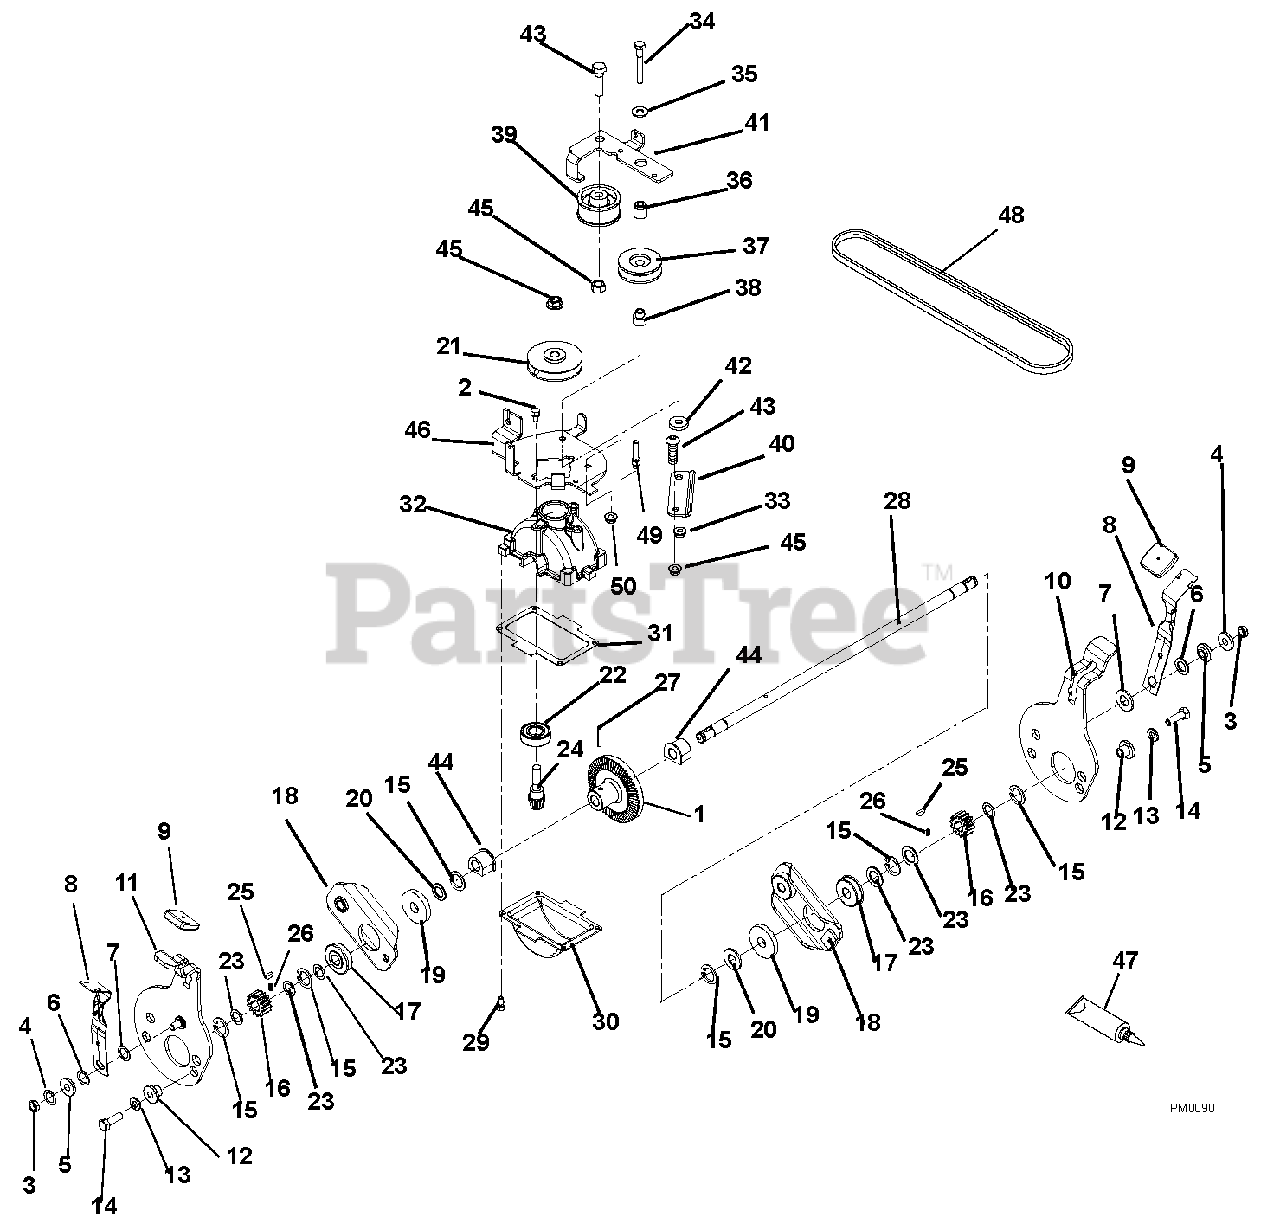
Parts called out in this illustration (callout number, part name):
1	Gear, Reduction
2	Screw, Tapping 10-24 x .375 Hex Washer Head Thread Rolling
3	Nut, Locking-Center .31-18
4	Washer, Flat-Steel .38 x .875 x .083
5	Bushing, Flange .265 x .437 x .250 x .750
6	Washer, Flat-Steel .52 x .827 x .062
7	Washer-Flat-Steel .630 x 1.005 x .062
8	Lever, Height Adjustment
10	Plate, Detent Support Right
11	Plate, Detent Support Left
12	Bushing, Flange .325 x .500 x .513 x .875
13	Washer, Locking .31 x .078 Regular
14	Bolt, Hex .31-18 x 1.00 Grade 5
15	Ring, Retaining-Internal .50 x .049
16	Pinion, WBLM Drive
17	Bearing, Ball .50 x 1.38 x .438 Sealed
18	Arm, Wheel Mount
19	Washer, Flat-Steel .515 x 1.625 x .250
20	Washer, Flat-Steel .531 x 1.06 x .095
21	Half, Transmission Input Pulley
22	Bearing, Ball .625 x 1.375 x .43
23	Washer, .500 x .750 x .020 Thrust
24	Pinion, Gearbox Input
25	Key, Woodruff .125 x .50 x .20
26	Spring, .134 x .186 x .144 Compression
28	Shaft, Transmission Output
29	Screw, Tapping 10-24 x .375 Hex Washer Head
30	Sump, Gearbox
31	Gasket, Transmission
32	Casting, WBLM Gear Box
33	Nut, Locking Top Flange .25-20
34	Bolt, Hex .25-20 x 2.25 Grade 8
35	Washer, Flat Steel .328 x 1.0 x .094
36	Spacer, .390 x .75 x .189
37	Idler, 3L Front Side .38 x 1.875
38	Spacer, Idler Pulley
39	Idler, Flat 1.875OD x .75 Wide
40	Strap,Transmission
41	Arm, Transmission Idler
42	Washer, Flat Steel .406 x .812 x .065
43	Bolt, Hex .38-16 x 1.25 Grade 5
44	Bushing, Transmission Output Shaft
45	Nut, Locking-Top-Flange .38-16
46	Bracket, Transmission Control
47	Lubricate
48	V-Belt 3L 35.98
49	Finger, Belt
50	Nut, Locking-Flange .250-20
